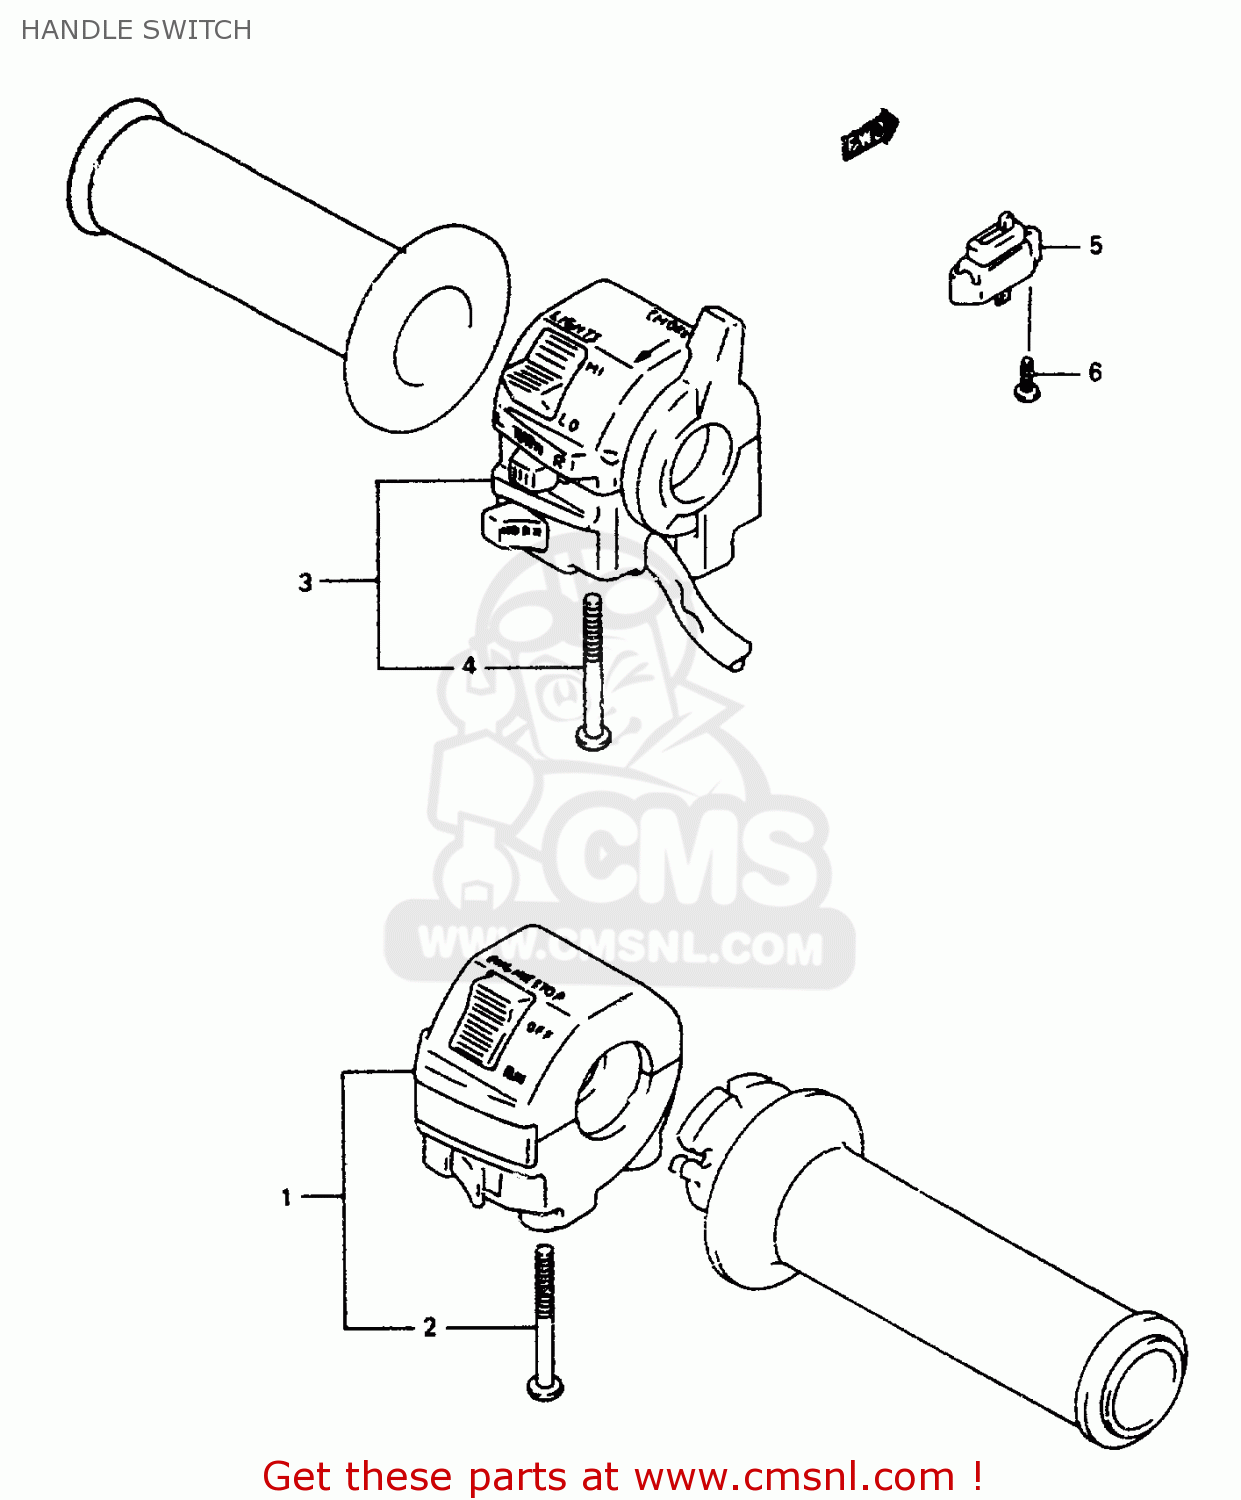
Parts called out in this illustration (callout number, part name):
1	SWITCH ASSEMBLY,HANDLE,RIGHT
2	SCREW, 5X45
3	SWITCH,HANDLE,
4	SCREW, 5X45
5	SWITCH ASSY,CLUTCH
6	SCREW
